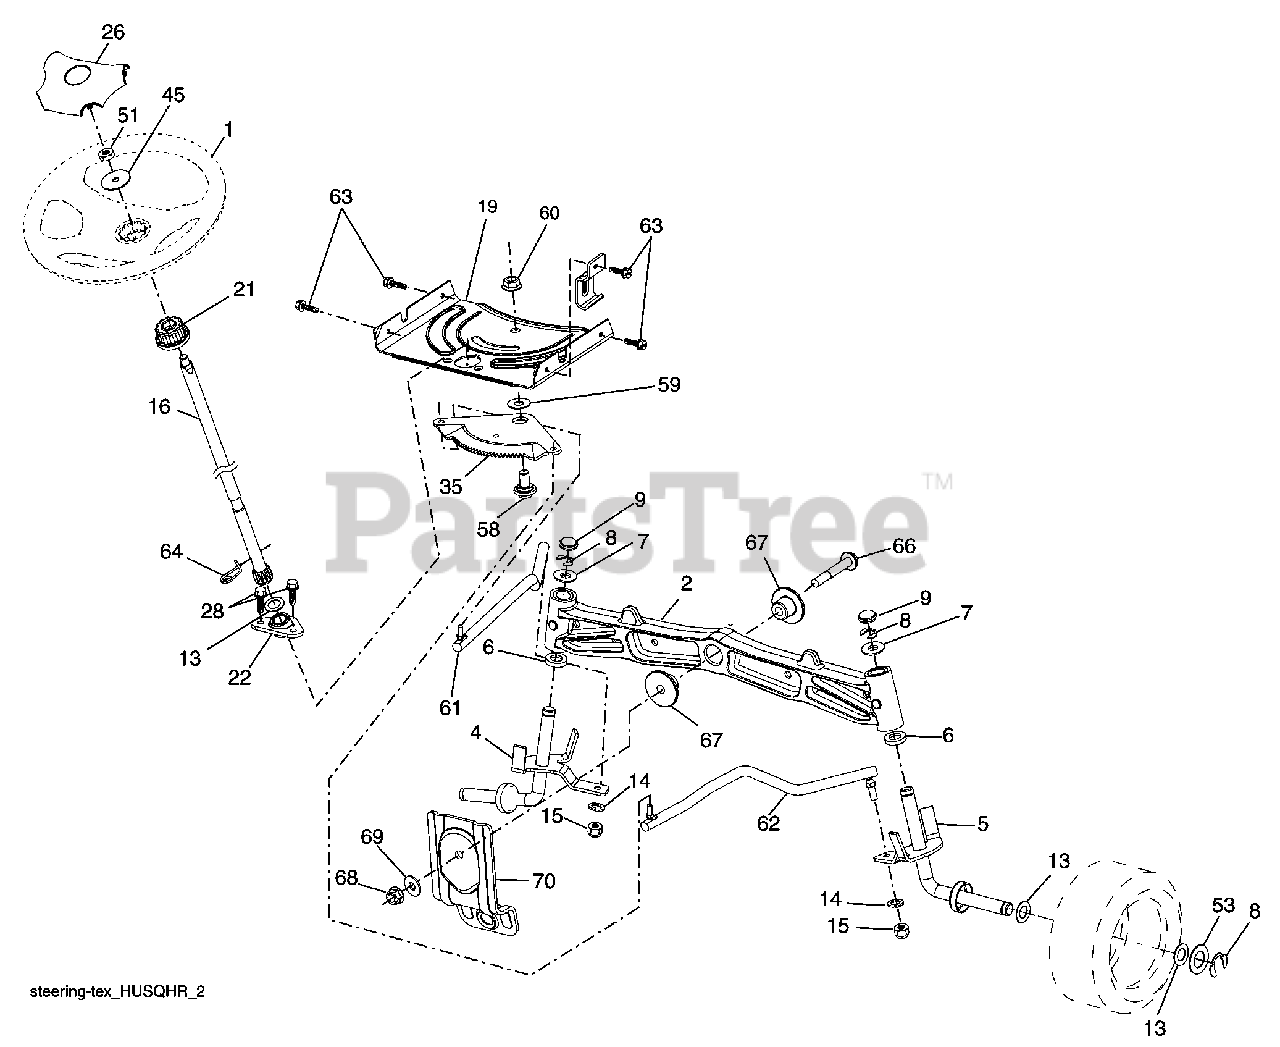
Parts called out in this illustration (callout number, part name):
1	Wheel, Steering
2	Axle Asm., Front
4	Spindle Asm., LH
5	Spindle Asm., RH
6	Washer Thrust .75 x 1.230
7	Washer 25/32 x 1-5/8 x 16 Ga.
8	Ring, Clip #T5304-75
9	Cap, Spindle
13	Washer 25/32 x 1-1/4 x 16 Ga.
14	Washer, Lock Hvy Hlcl Spr 3/8
15	Nut, Crown Lock 3/8-24 unf
16	Shaft Steering
19	Plate Steering
21	Adapter, Wheel Steering
22	Bushing, Strg. Blk
26	Insert, Wheel Steering
28	Screw 3/8-16 x 3/4
35	Gear, Sector Plate
45	Washer 9/16 ID x 2-3/8 OD 12 Ga.
51	Nut Hex Jam Toplock 1/2-20 unf
53	Washer Hardened .793 x 1.637 x .060
57	Bracket Upstop
58	Bolt Shoulder Sector Pivot CFM
59	Washer Thrust Sector Steering
60	Nut Flange Lock 5/8-11
61	Draglink LH
62	Draglink, RH
63	Screw 5/16-18 x 3/4
64	Retainer Clip Spring Steering
66	Bolt Hex Fghd 7/16-14 x 3 Serr
67	Bushing PM Front Axle
68	Nut Lock Flange 7/16-14 Gr. 5
69	Washer 1.5 x .505 x .118
70	Bracket Deck Susp. Front
